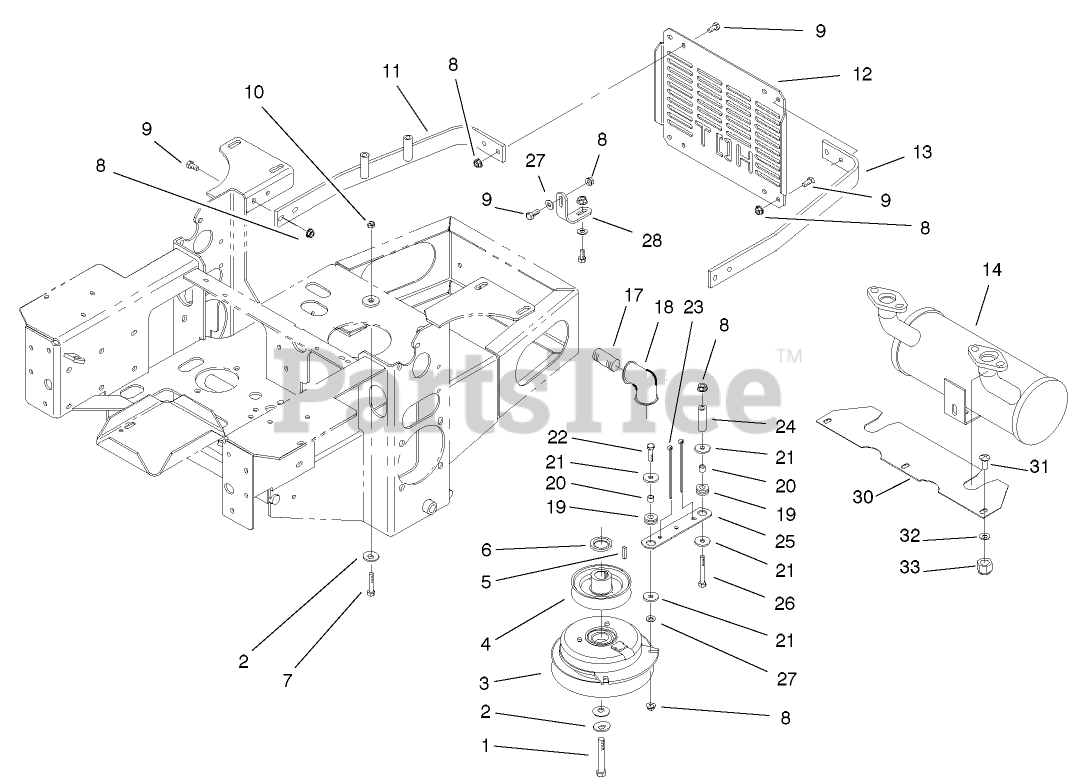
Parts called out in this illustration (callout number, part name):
1	SCREW-HH
2	WASHER-SPRING
3	Clutch,Mag Stop
4	PULLEY
6	SPACER-CRANKSHAFT
7	SCREW-HH
8	NUT-HF
9	SCREW-HH
10	NUT-HF
11	STRAP-GUARD, ENGINE
12	SHIELD-ENGINE
13	STRAP-GUARD, ENGINE
14	Muffler,18kc Vertical
17	NIPPLE,PIPE
18	ELBOW-90 DEG
19	GROMMET
20	SPACER
21	WASHER
22	SCREW-HH
23	TIE-PLASTIC
24	BUSHING-MOUNT, SEAT
25	STRAP-CLUTCH, BRAKE
26	SCREW-HH
27	WASHER-FLAT
28	BRACKET-SUPPORT, MUFFLER
30	Shield,Heat
31	BOLT-CARR
32	WASHER-PLAIN
33	NUT-LOCK, NI
